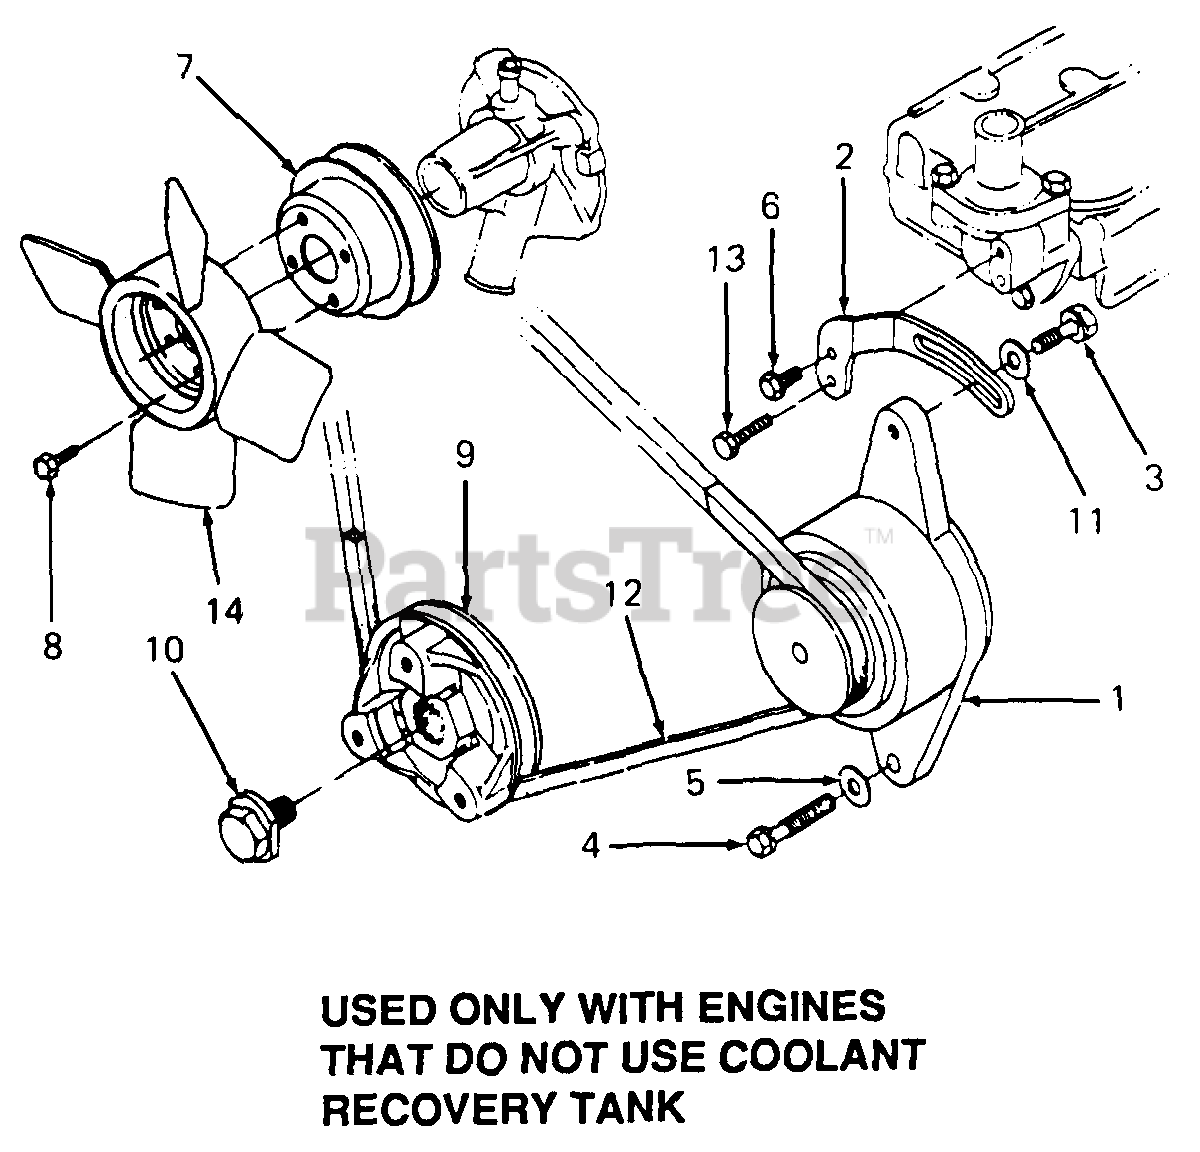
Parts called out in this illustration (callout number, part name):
1	Alternator
2	Support, Alternator
3	Screw w/Washer
4	Screw w/Washer
6	Screw w/Washer
7	Pulley, Water Pump
8	Screw, Hex Washer Head
9	Pulley, Alternator Drive
13	Screw w/Washer
